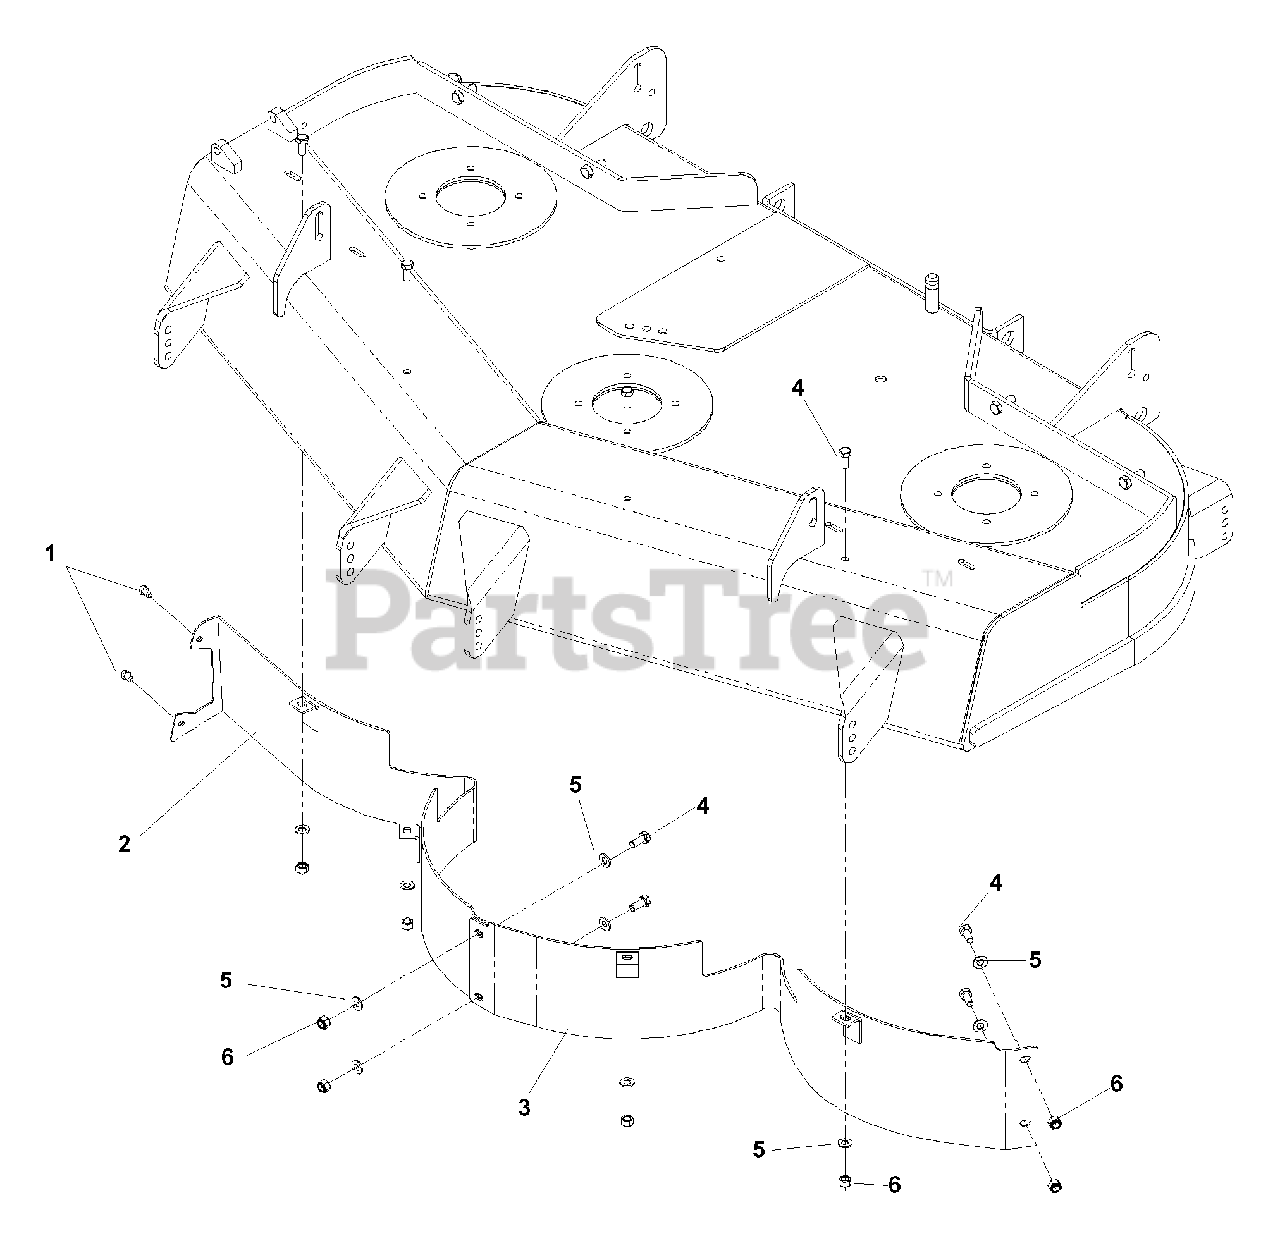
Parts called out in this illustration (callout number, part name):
1	SCREW, 1/4 -20 x 1/2, TAP
2	BAFFLE, RIGHT, 72" DECK
3	BAFFLE, LEFT, 72" DECK
4	HCS, 5/16 -18 x 3/4,
5	WASHER, 5/16, SAE
6	NUT, 5/16 -18, NYLOC
